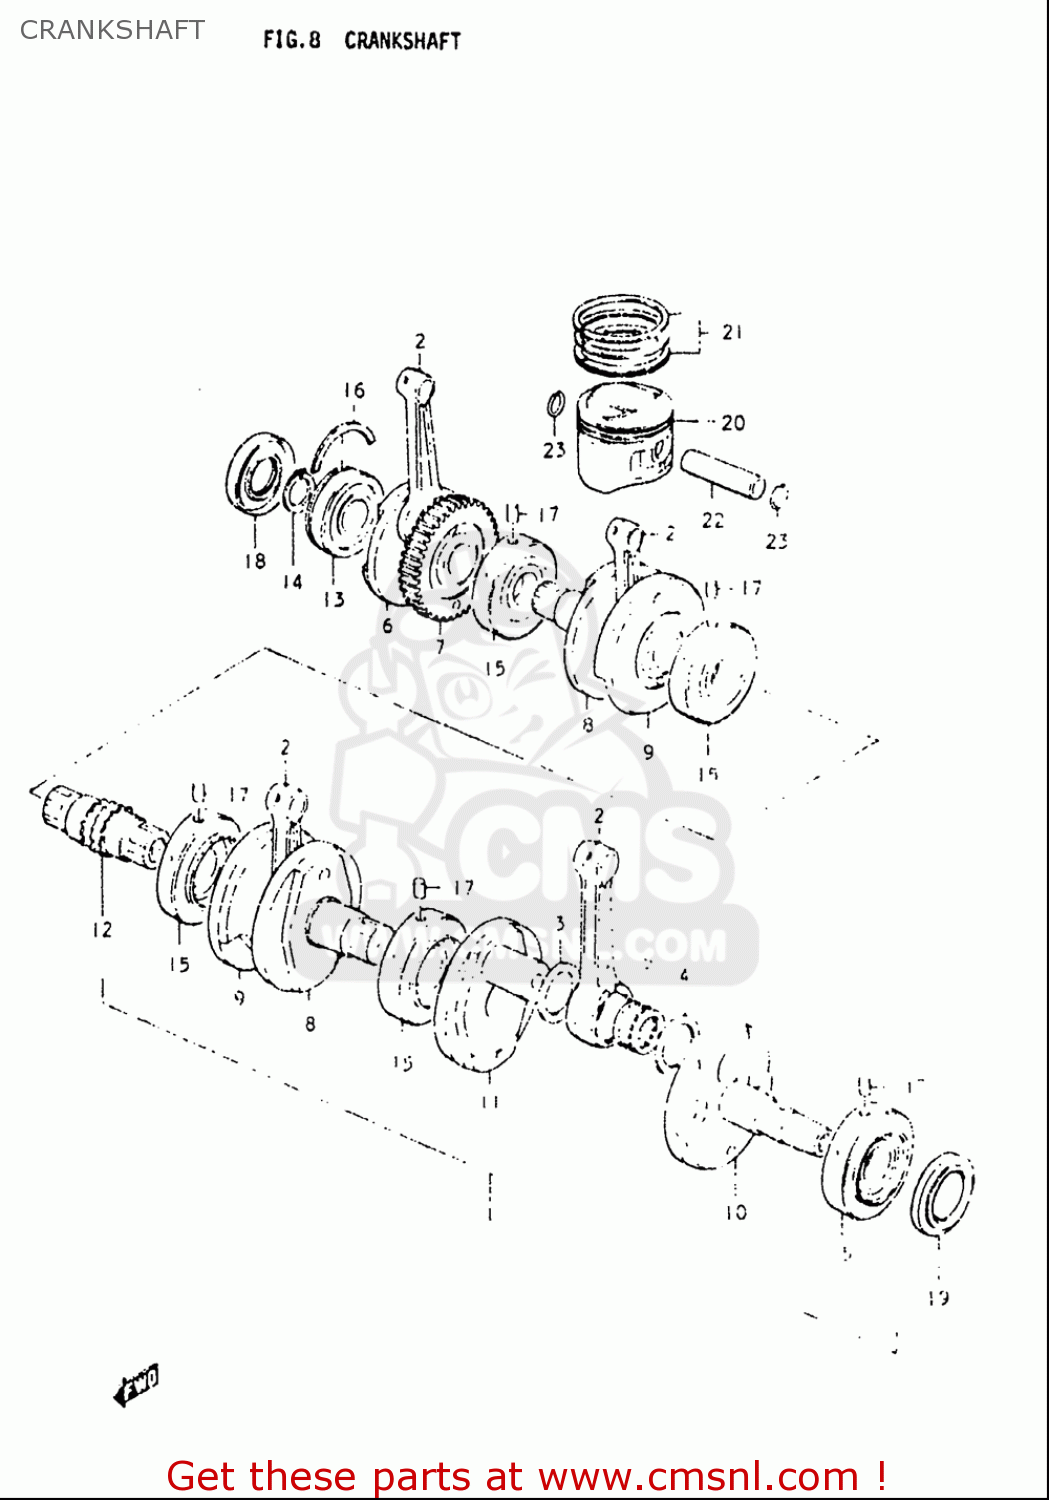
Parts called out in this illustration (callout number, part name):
3	WASHER (28X48X2)
13	BEARING(30X72X19)
14	CIRCLIP
15	BEARING(32X72X21)
16	C RING
17	PIN
18	SEAL,OIL(30X72X11)
19	SEAL,OIL(47.3X60X6.5)
20	PISTON
21	RING SET,PISTON
22	PIN,PISTON 16MM
23	RING,SNAP 16MM
